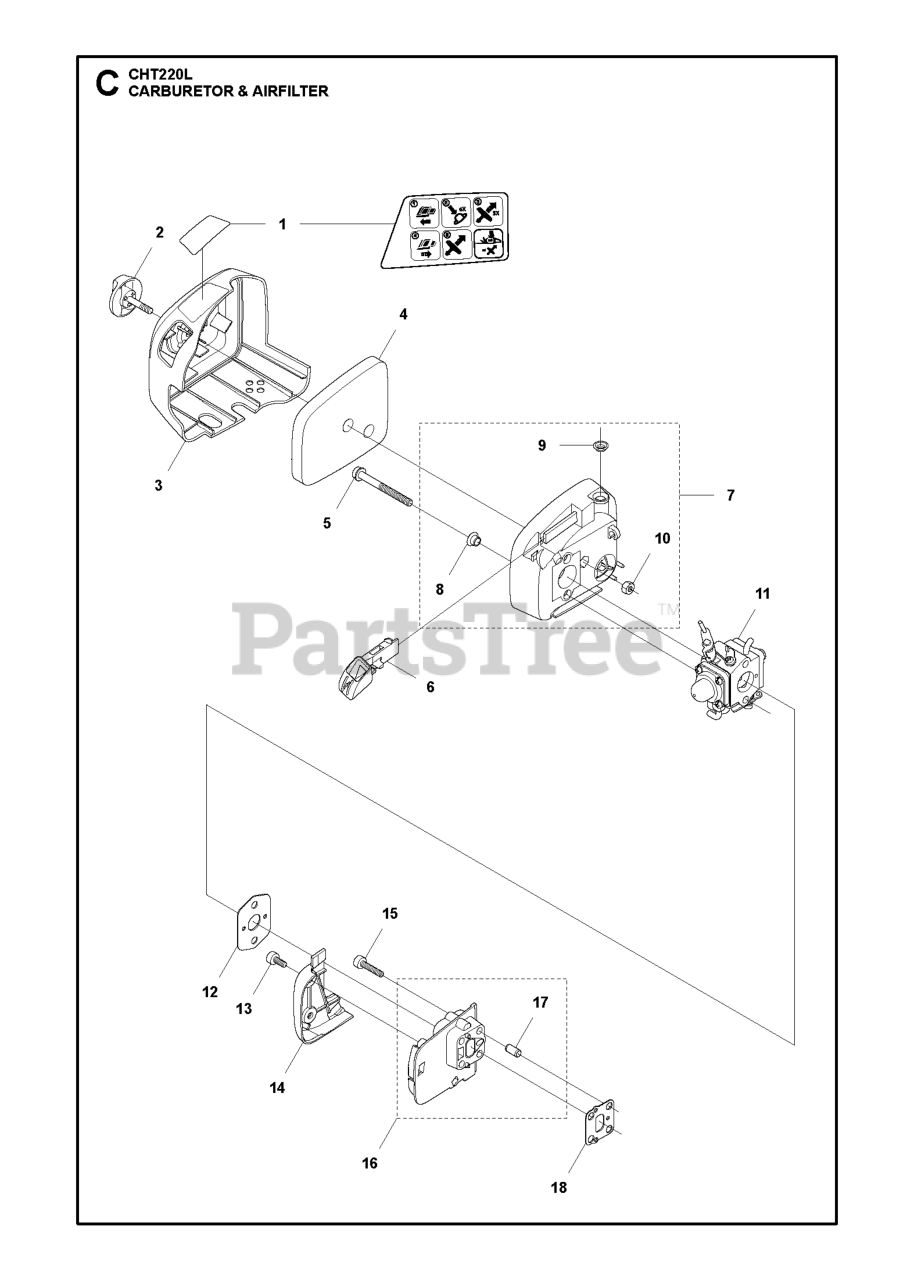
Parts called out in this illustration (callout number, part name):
3	COVER AIR FILTER
4	AIR FILTER
7	FILTER HOLDER ASSY.
8	RIVET TUBULAR
9	RIVET TUBULAR
11	CARBURETOR ASSY.
16	MANIFOLD
17	TUBULAR RIVET
